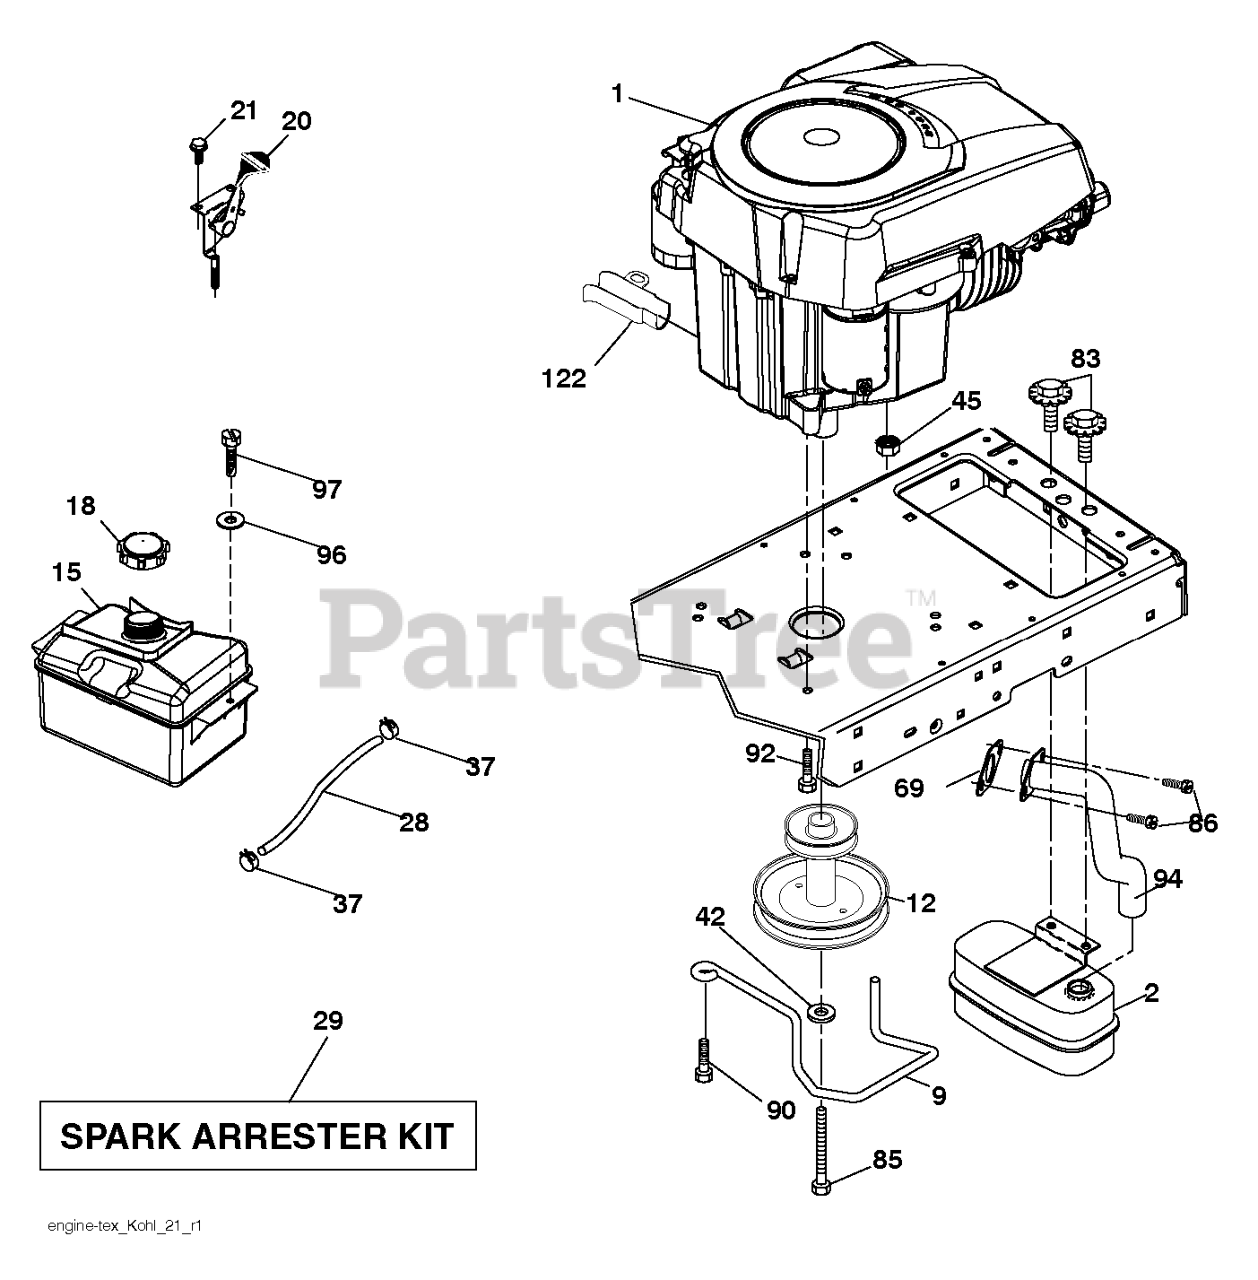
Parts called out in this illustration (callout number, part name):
2	MUFFLER.SINGLE.CYL.KOHL/B&S
9	KEEPER.BELT.ENGINE.4.2
12	PULLY ENGINE
15	RP TANK FUEL FRT 1.5 GAL
18	CAP ASM.FUEL.2.25"FR.
20	CONTROL.TH/CK.C.
21	SCREW.#10 X 0.750.BOS
28	LINE.FUEL.20
29	KIT.SPARK ARRESTOR 794945 B&S
37	HOSE CLAMP
42	LOCKWASHER
45	NUT
69	GASKET.EXHAUST.KOHLER
83	BOLT.5/16-18UNCX3/4 W/SEMS.BLK
85	BOLT HEX 7/16-20X4-1/4"
86	SCREW.SOCKET HD.5/16-1
90	SCREW 3/8-16X1
92	SCREW 3/8-16X1
94	RP.TUBE.EXHAUST.KOHL.COURAGE
97	SCREW HEXWSHR 1/4-20X3/4
122	EXTENSION DRAIN OIL
